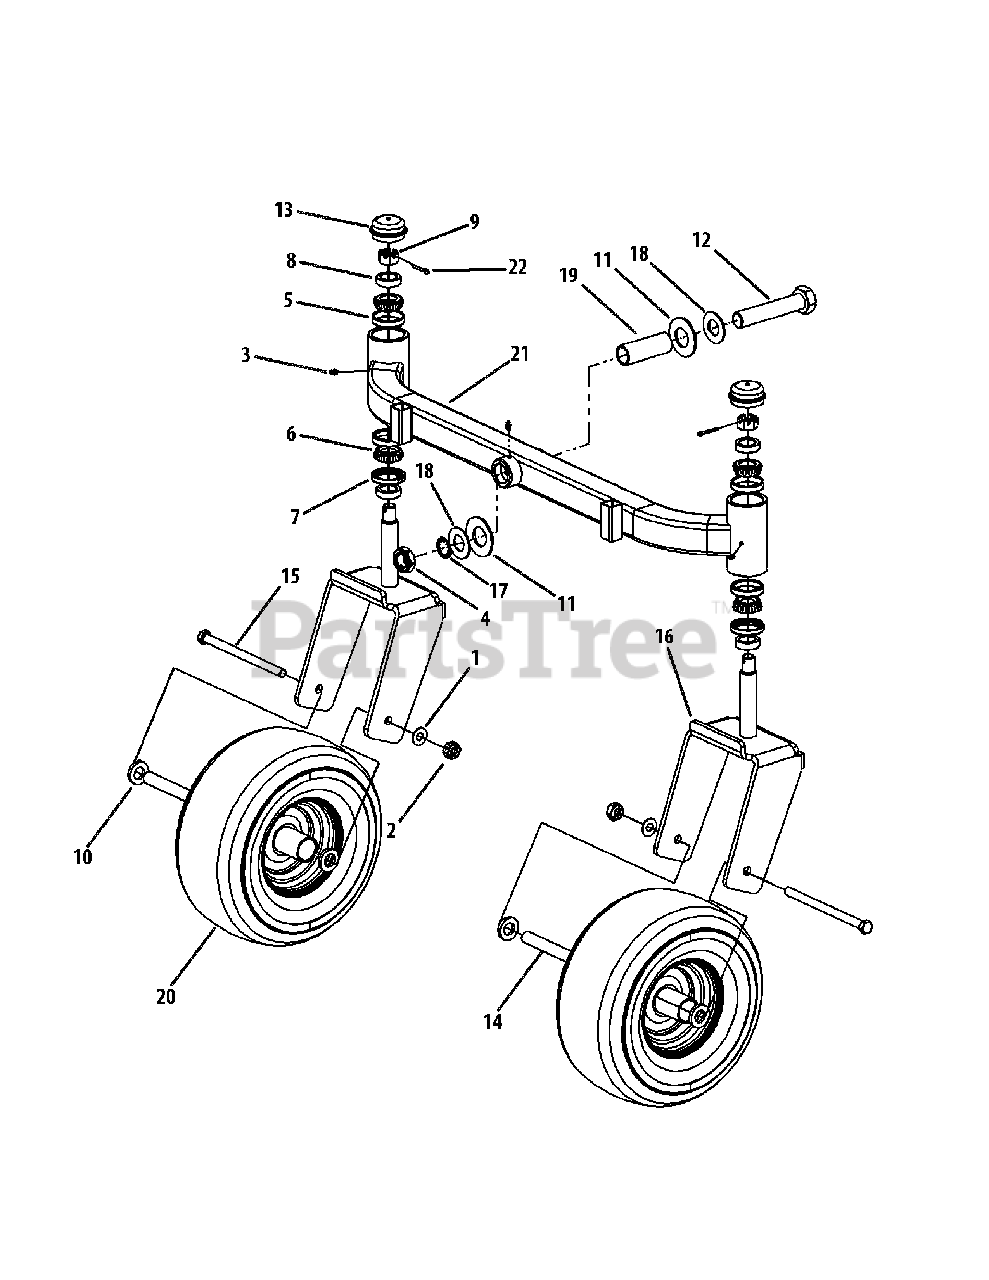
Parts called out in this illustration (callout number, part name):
1	Washer, 1/2 x 1 Shim
2	Nut, 1/2-20, Center Lock
3	Grease Fitting, 1/4-28 x 3/16
4	Nut, Jam, 1.0-14, Insert Lock
5	Cup Bearing
6	Bearing Cone
7	Seal
8	Ring Seal
9	Slotted Nut, 3/4-16
10	Spacer, .812 ID x .218LG
11	Bell Washer, 1.25 ID x 2.5 x .157
12	Hex Cap Screw, 1-14 x 5.0
13	Grease Cap, 1.986 OD
14	Wheel Spacer
15	HHCS, 1/2-20, 7.50
16	Yoke, Caster Wheel
17	Retainer Extension, Self Locking
18	Flat Washer, 1.00 ID
19	Spacer, 1.005 ID x 1.25 OD x 3.6
20	Wheel,13 x 6.50 x 6.0, Beige
20	Roller Bearings (per tire)
20	Retainer Bushings (per tire)
21	Front Axle Assembly 54"/60"
21	Front Axle Assembly 72"
22	Cotter Pin, 5/32, 1.25
